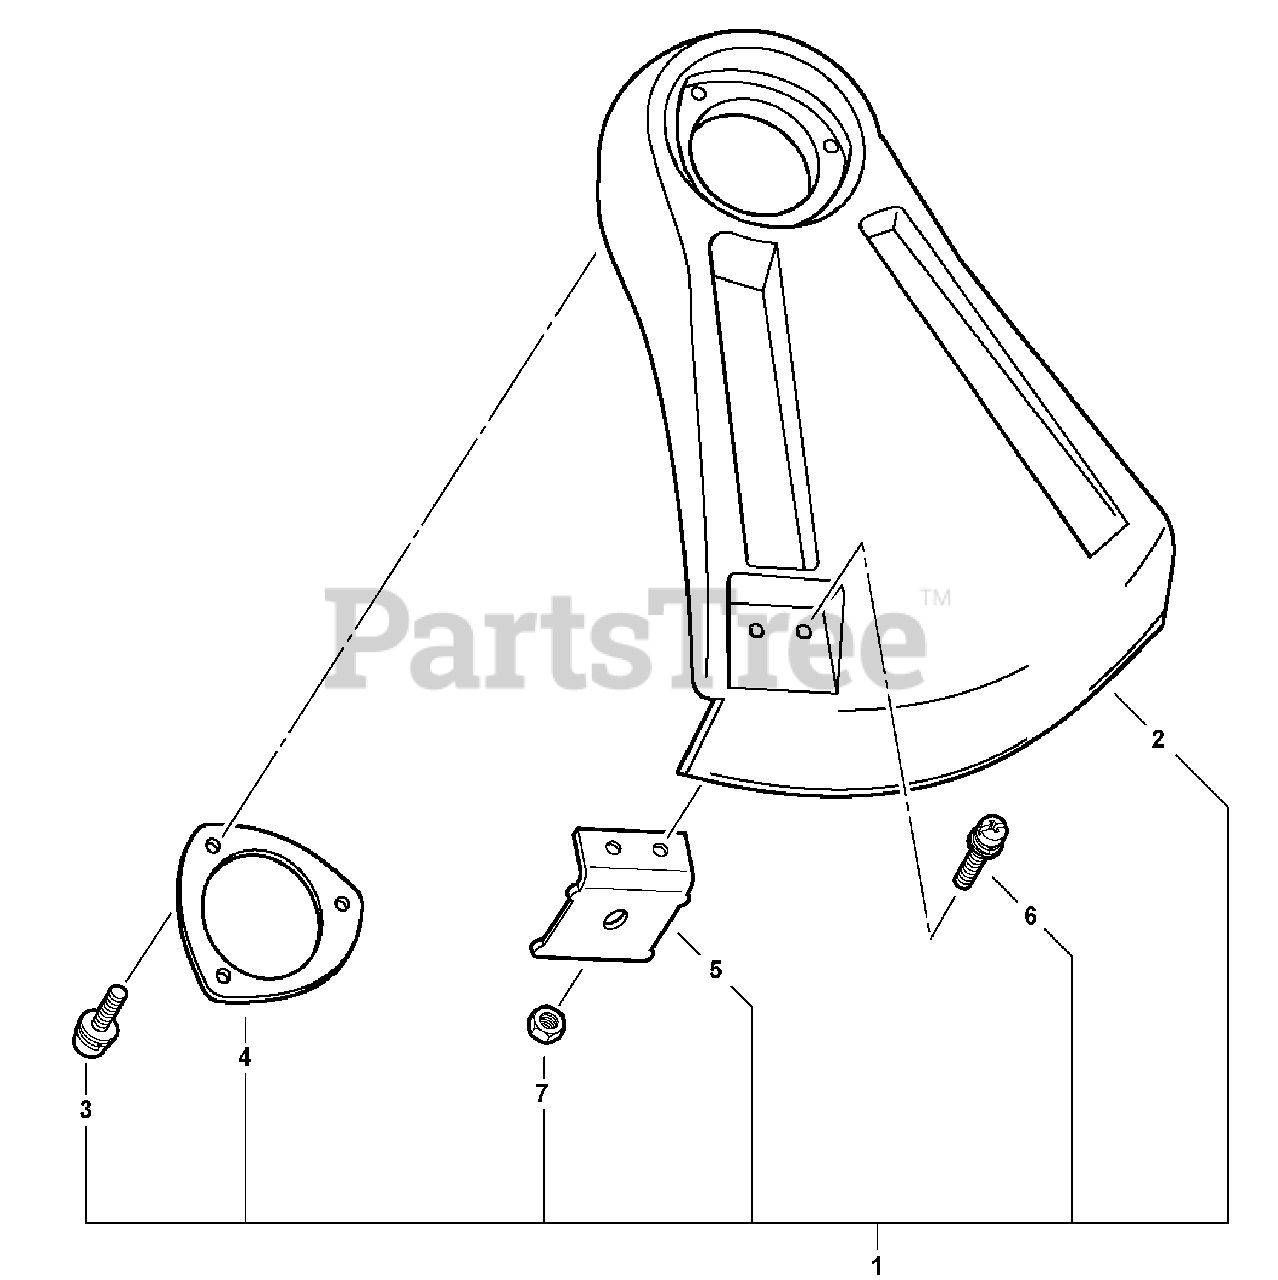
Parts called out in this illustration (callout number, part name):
1	DEBRIS SHIELD KIT
2	SHIELD, DEBRIS
3	SCREW 5×20
4	PLATE, SHIELD Ø49.5 MM
5	CUTTER, LINE
6	SCREW 5×16
7	NUT M5
